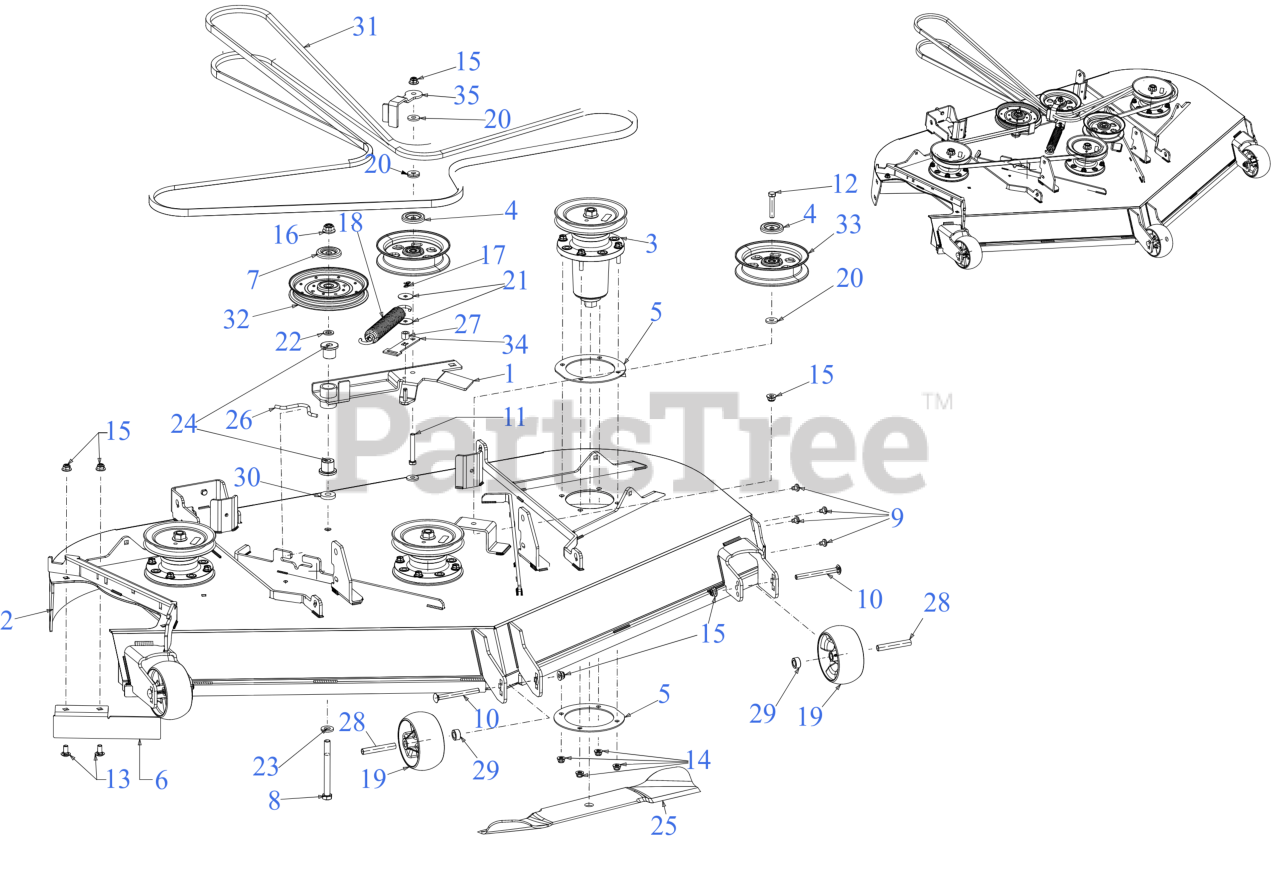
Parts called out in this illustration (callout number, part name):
1	54/60" DECK IDLER ASSEMBLY
2	60" FAB DECK SHELL
3	SPINDLE ASSEMBLY
3	Cub Cadet 60" SPINDLE ASSEMBLY (07386)
4	PULLEY CAP 1.875 DIA
5	SPINDLE PLATE
6	60" DECK CHUTE BAFFLE
7	PULLEY CAP (.540 x 2.041 DIA)
8	BOLT-HEX 1/2-13X5.0 GR5
9	SCREW 5/16-18 x .375
10	CARRIAGE BOLT 3/8-16 x 4.00 GR5
11	HEX SCREW-3/8-16X2.5 GR5
12	SCREW 3/8-16 x 2.0 GR5
13	CARRIAGE BOLT 3/8-16 x .75
14	FLANGE LOCK NUT 5/16-18
17	BOW TIE COTTER PIN 1/4-5/16
18	SPRING 1.25" DIA x 8.5" LONG
19	DECK WHEEL
19	WHEELS-DELUXE 5"
20	FLAT WASHER .385 x 1.00 x .135
21	FLAT WASHER .322 ID x 1.25 x .060
22	FLAT WASHER
23	FLAT WASHER .531X1.060X.134
24	FLANGE BEARING
25	21" BLADE
26	DECK SPRING HOOK
27	SPACER
28	SPACER .38X.49X3.05LG
29	SPACER-.505 1D
30	SPACER PLATE
31	V-BELT B SEC x 162.25
32	IDLER PULLEY 6.0" DIA
33	5" FLAT IDLER PULLEY
34	BELT KEEPER
35	54/60" IDLER KEEPER
